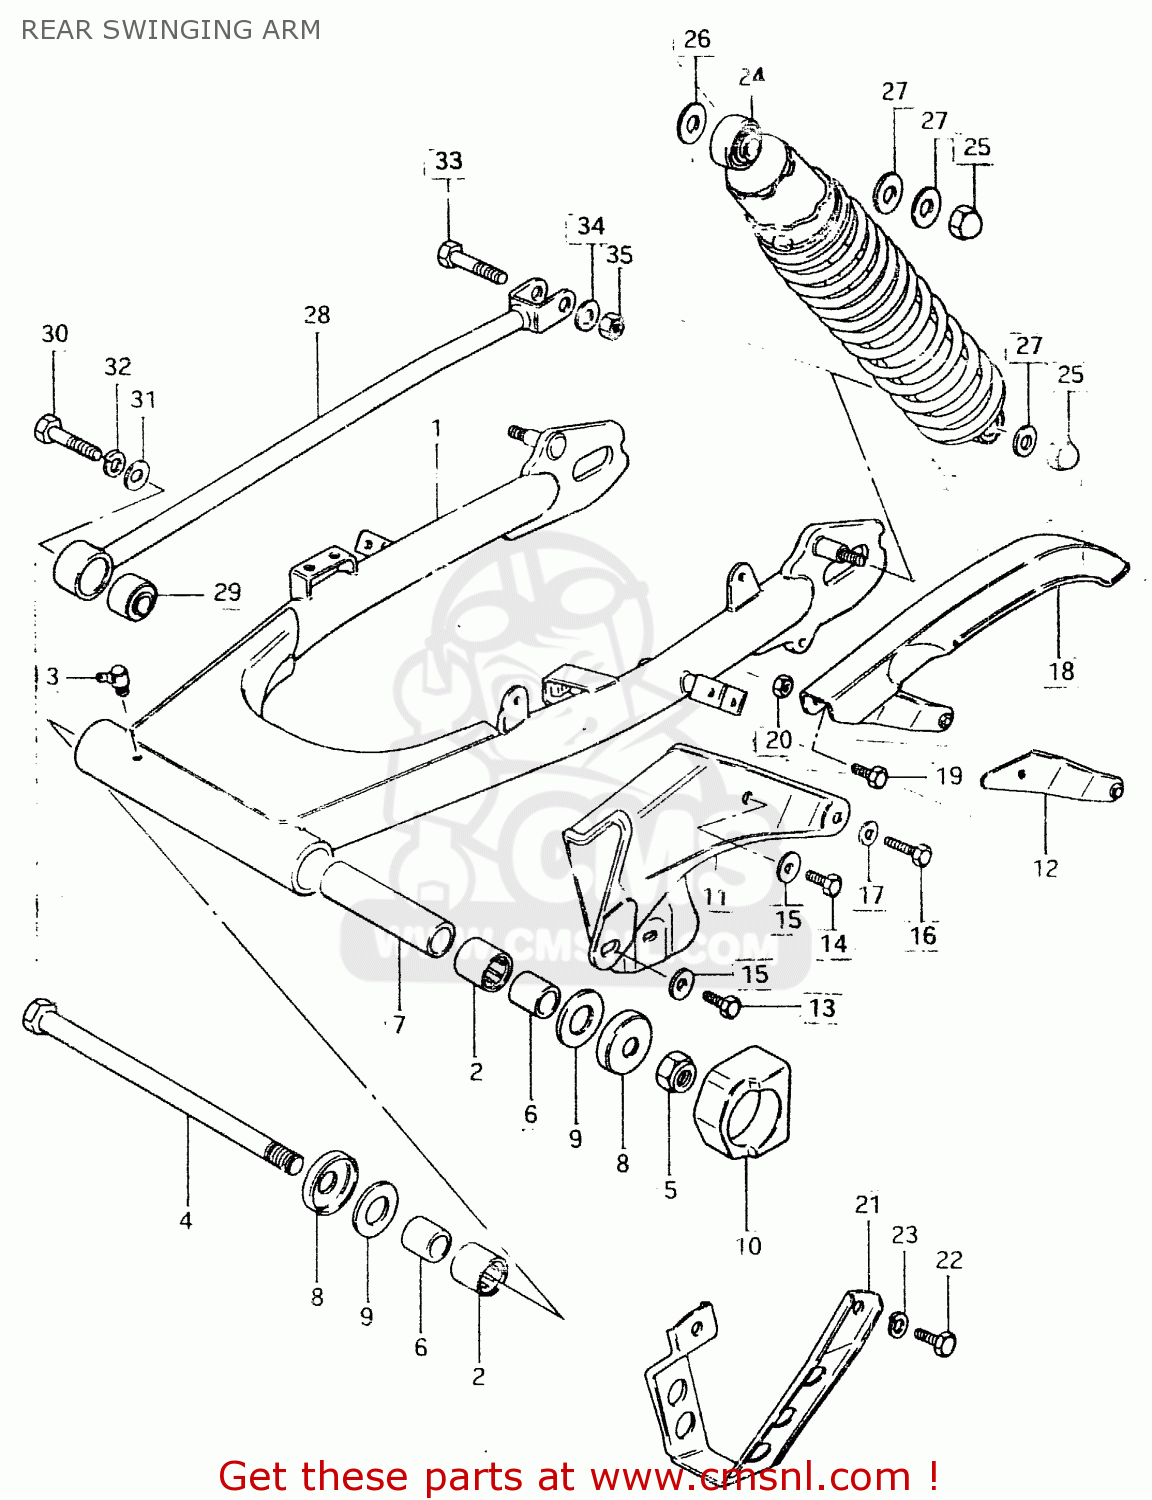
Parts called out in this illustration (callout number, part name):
1	REAR SWINGING ARM SET
2	BEARING(22X29X20)
3	NIPPLE,GREASE
4	SHAFT,REAR SWING ARM
5	NUT 16MM
6	SPACER,RR SWGARM PIVOT
7	SPACER (16.2X21.7X142)
8	COVER,RR SWGARM DUST SEAL
9	WASHER
10	BUFFER,CHAIN TOUCH DEFENSE
11	CASE,CHAIN
12	REINFORCEMENT,CHAIN CASE
13	BOLT
14	BOLT(6X8)
15	WASHER
16	BOLT, UPPER
17	WASHER
18	CHAIN CASE, END
19	BOLT
20	NUT
21	GUIDE,CHAIN
22	BOLT 8X12
23	LOCK WASHER
24	ABSORBER ASSEMBLY,REAR SHOCK
25	NUT, LOWER LH
26	WASHER
27	WASHER
28	TORQUE LINK,REAR
29	BUSH
30	BOLT 10X40
31	WASHER
32	LOCK WASHER
33	BOLT 10X40
34	WASHER
35	NUT
